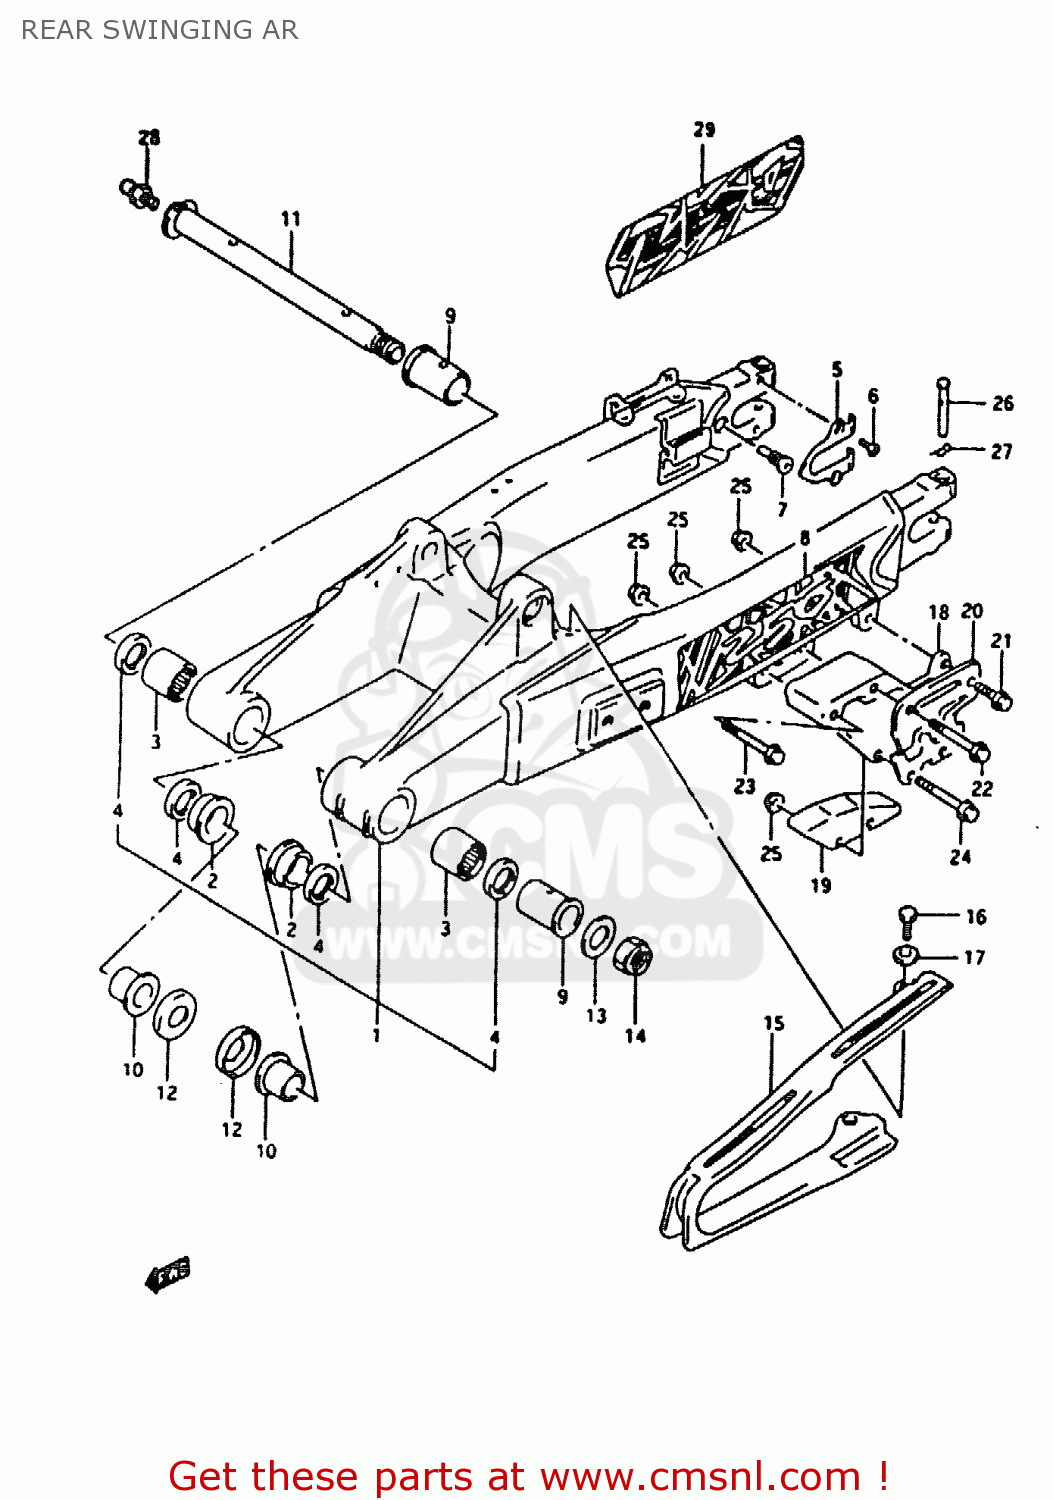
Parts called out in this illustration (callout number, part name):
1	SWING ARM ASSEMBLY,REAR
2	BUSHING,SWGARM PIVOT
3	BEARING(22X29X30)
4	SEAL,OIL(22X29X4)
5	PLATE,RR SWING ARM AXLE
6	SCREW(5X8)
7	SCREW (M10X21)
8	EMBLEM, 250
9	SPACER,RR SWGARM PIVOT
10	SPACER,SWGARM PIVOT INNER
11	SHAFT COMP,SWING ARM PIVOT
12	COVER,SWINGINGARM PIVOT
13	WASHER, FIXED DRIVE FACE
14	NUT
15	BUFFER,CHAIN TOUCH DEFENSE
16	BOLT
17	WASHER
18	GUIDE,CHAIN
19	DEFENSE,CHAIN GUIDE
20	PLATE,CHAIN GUIDE OUTER
21	BOLT,G/S SWITC
22	BOLT
23	BOLT
24	BOLT
25	NUT
26	PIN
27	CLIP
28	NIPPLE
29	EMBLEM,SWING ARM,LEFT
